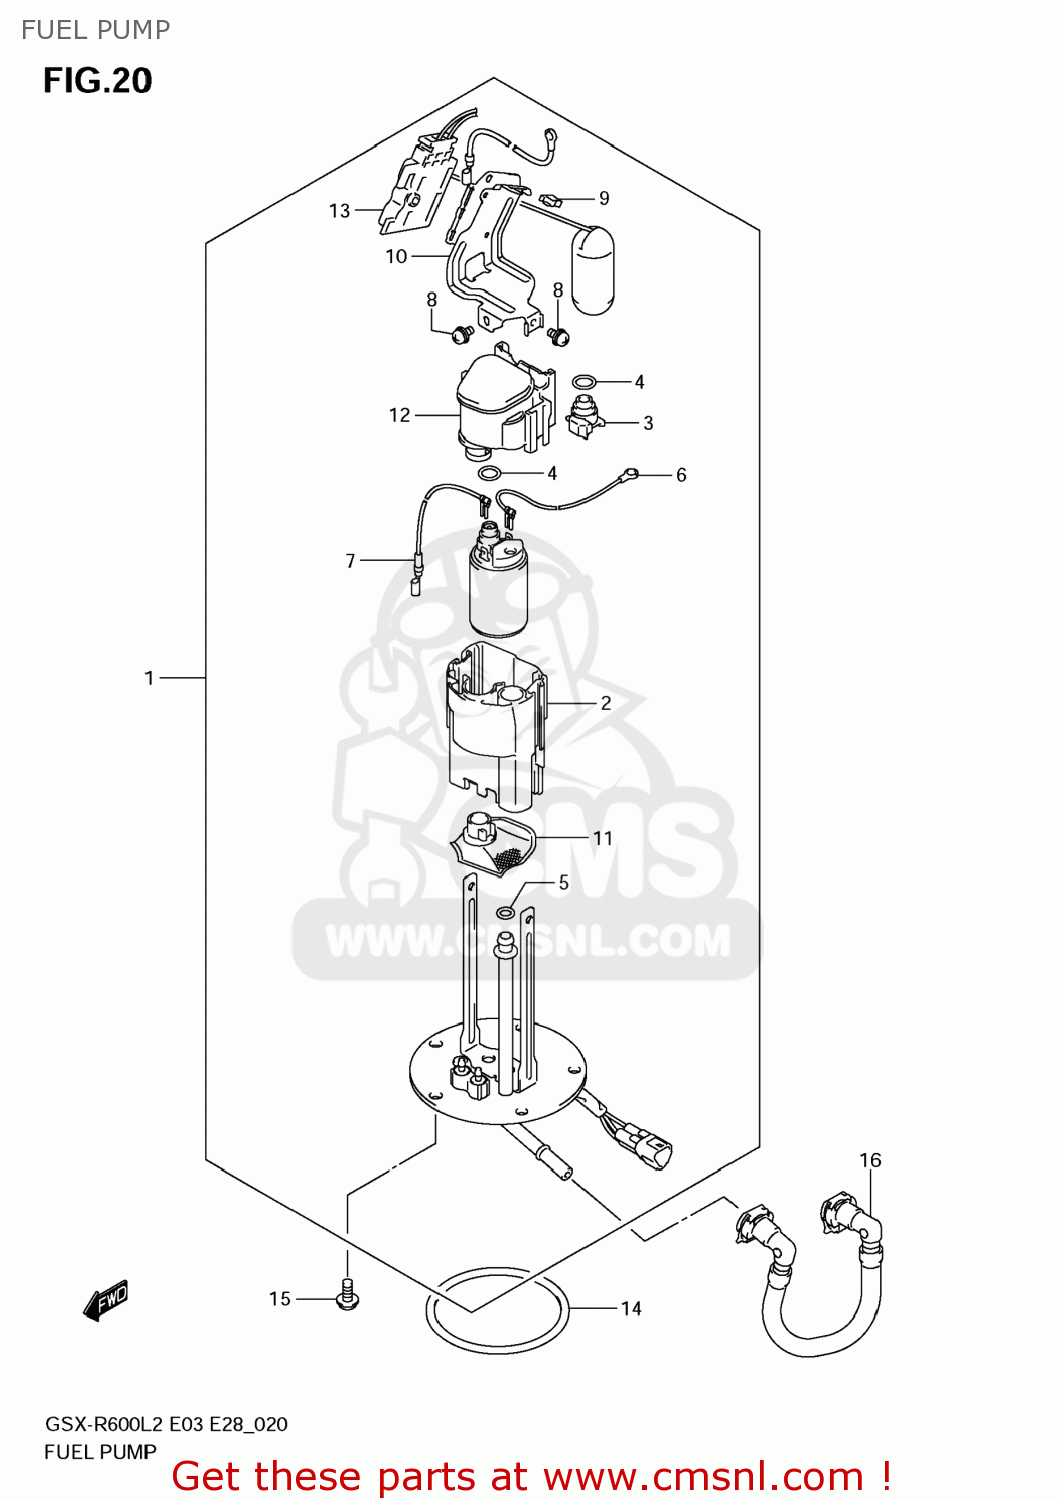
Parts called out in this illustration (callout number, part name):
1	PUMP ASSY,FUEL
2	CUP
3	JOINT
4	O RING
5	O RING
6	WIRE,EARTH
7	WIRE,LEAD
8	SCREW
9	SADDLE,EDGE
10	BRACKET,GAUGE
11	STRAINER
12	REGULATOR,FUEL
13	GAUGE ASSY,FUEL LEVEL
14	O RING,FUEL PUMP
15	BOLT
16	HOSE,FUEL
